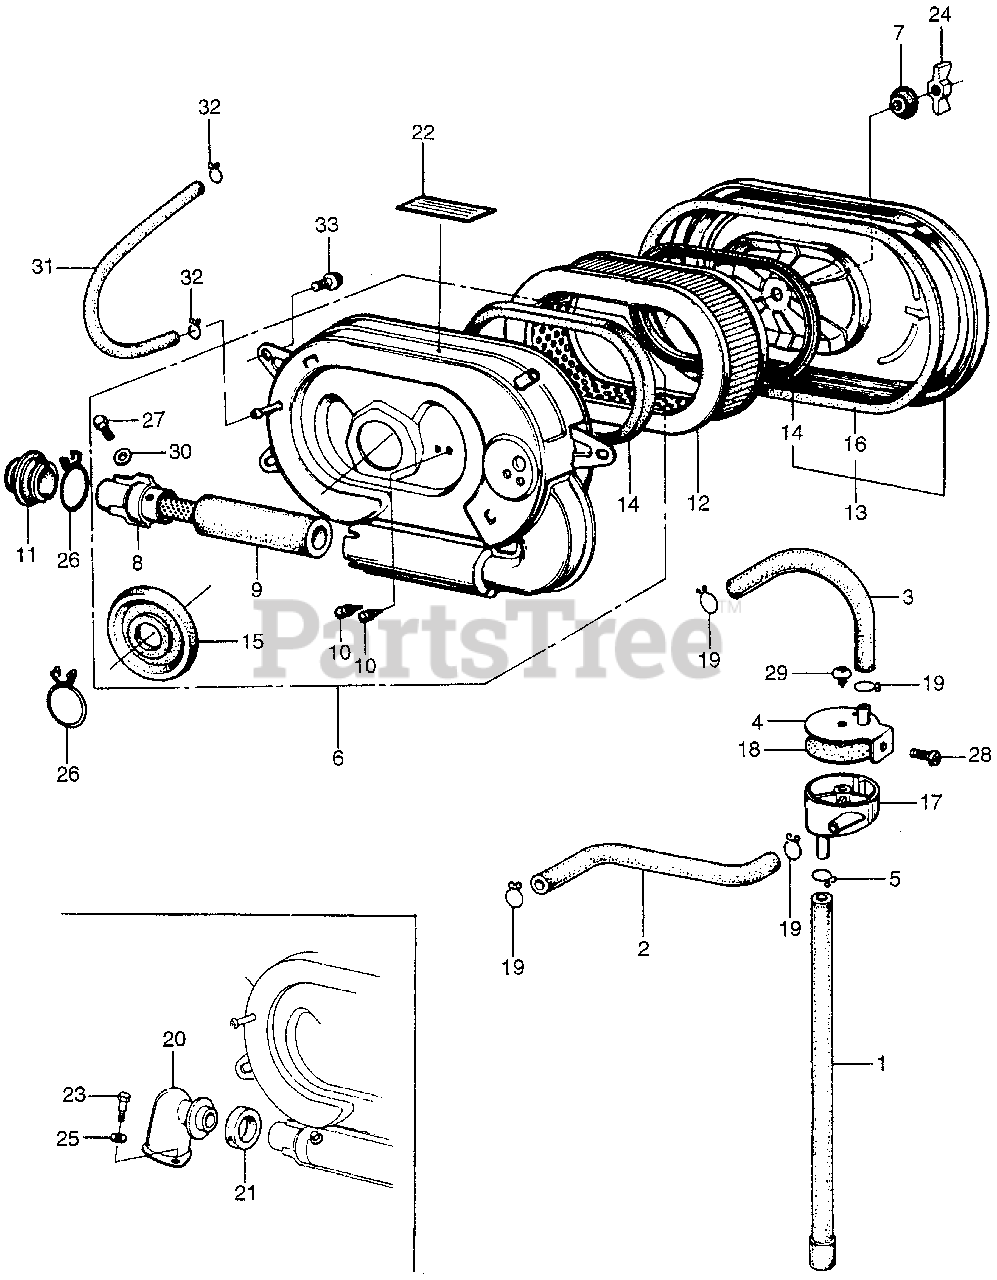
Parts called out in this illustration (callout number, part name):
1	TUBE, OIL DRAIN
2	TUBE, BREATHER
3	TUBE B, BREATHER
4	STAY, BREATHER
5	CLIP, BREATHER TUBE (NOT AVAILABLE)
6	CASE ASSY., CLEANER
7	WASHER, AIR CLEANER COVER
8	PIPE, INLET
9	POLYURETHANE (NOT AVAILABLE)
10	PLUG (4.5MM) (NOT AVAILABLE)
11	BOOT, CLEANER PIPE
12	ELEMENT, CLEANER (NOT AVAILABLE)
13	COVER, AIR CLEANER *NH19M* (DARK GRAY METALLIC)
14	GASKET, ELEMENT (NOT AVAILABLE)
15	GROMMET, AIR CLEANER CONNECTING
16	GASKET, CLEANER CASE
17	CHAMBER, BREATHER (NOT AVAILABLE)
18	GASKET, BREATHER
19	CLIP, BREATHER TUBE
20	VALVE ASSY., HOT AIR
21	SEAL, HOT AIR
22	MARK, AIR FILTER
23	BOLT, FENDER SETTING (NOT AVAILABLE)
24	WINGNUT, AIR CLEANER COVER
25	WASHER, FUEL FEED PIPE
26	CIRCLIP (34MM)
27	BOLT, HEX. (5X8)
28	SCREW, PAN (6X12)
29	SCREW, TAPPING (6X10)
30	WASHER, PLAIN (5MM)
31	BULK HOSE, FUEL (5.5X8000) (5.5X200)
32	CLIP, TUBE (B10)
33	BOLT, FLANGE (6X12)
